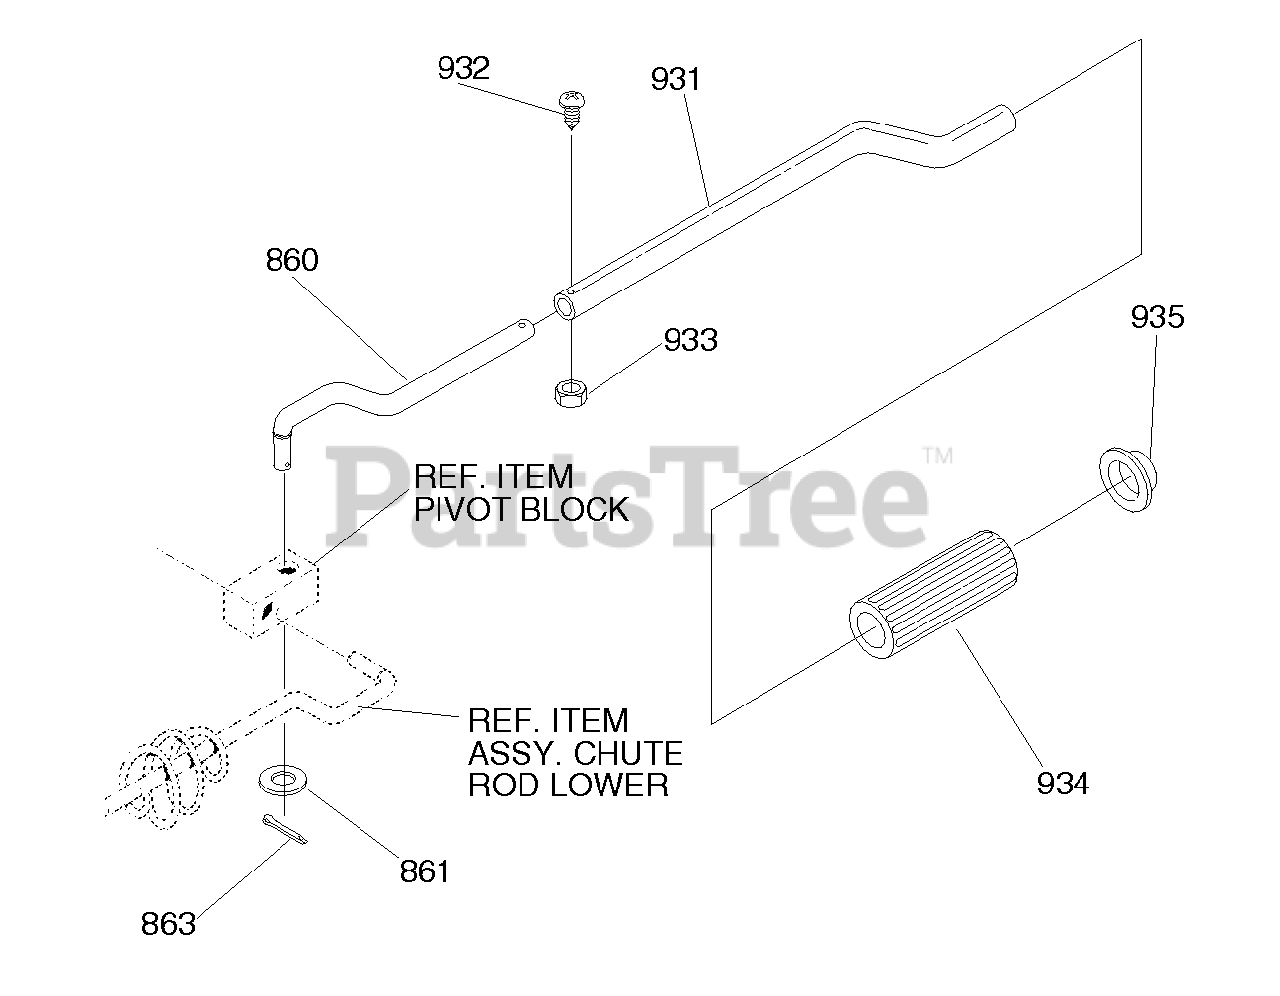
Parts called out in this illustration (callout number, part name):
860	ROD, MID CHUTE CTL
861	WASHER, FLAT .40 X .75 X .025
863	PIN, COTTER .090 DIAX .75 LG
931	ROD CHUTE CTRL UPR, ASSN
932	SCREW, 10-32 X .88 SLTRHD
933	NUT, #10-32 CTRLK
934	KNOB, CHUTE CRANK
935	NUT, PUSH, FITS 3/8 DIA
